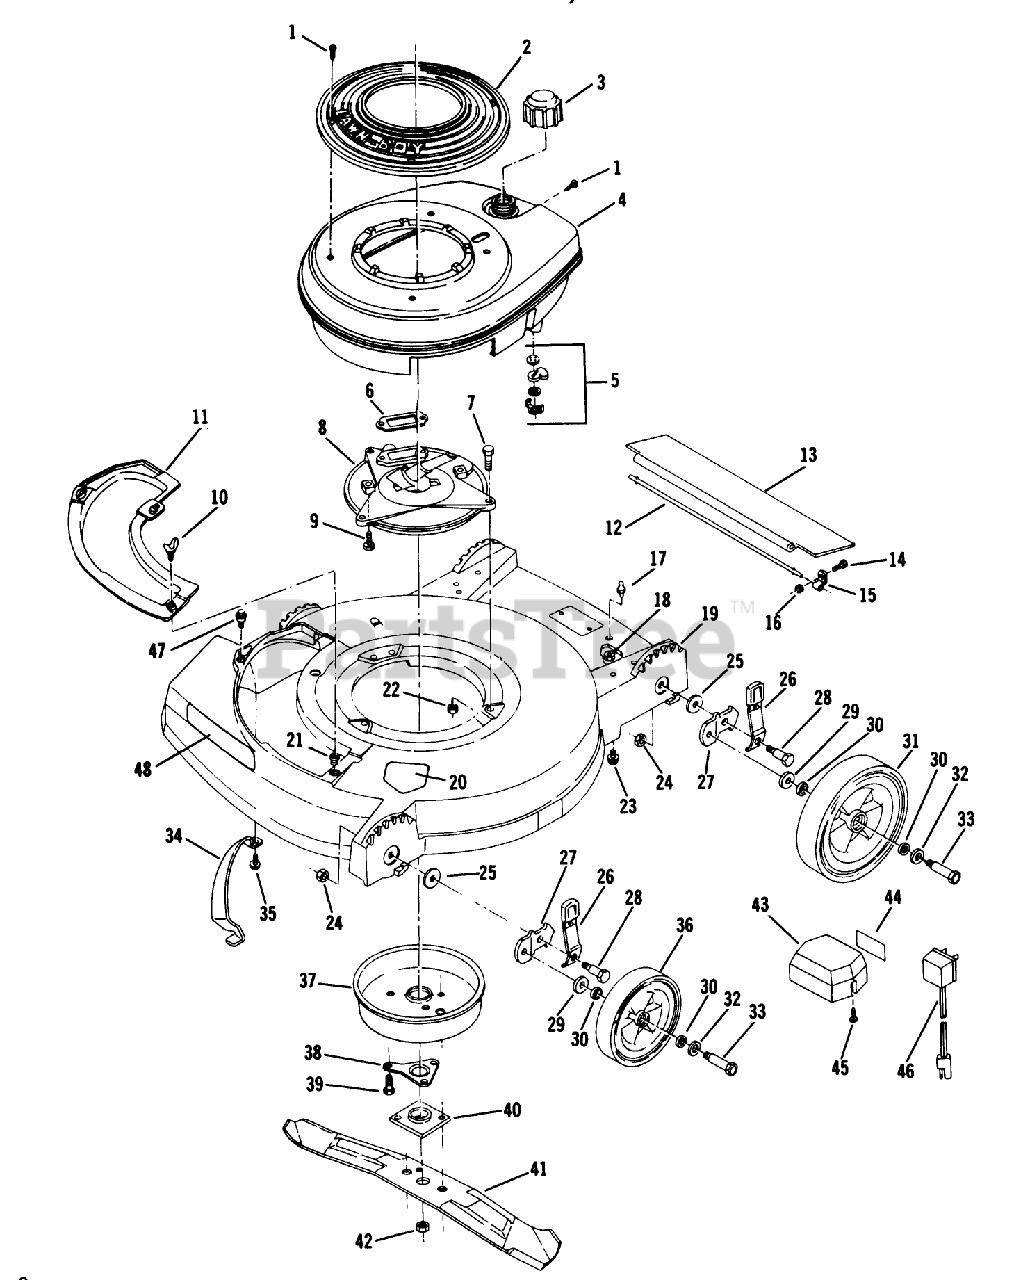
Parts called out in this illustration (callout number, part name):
1	SCREW - SELF TAPPING
3	FUEL CAP & INSERT
5	SHUT OFF VALVE KIT
7	SCREW-HH
9	SCREW V
10	WING SCREW LAWRE
12	ROD 21" ADVANCE
15	CLAMP ROD KMC
16	LOCKNUT E
22	NUT-LOCK F
24	LOCKNUT
29	WASHER WROUGHT
33	BOLT WHEEL
34	BAR-TOE
36	WHEEL & TIRE KIT
37	MUFFLER COVER F
38	SUPPORT F
40	PLATE AND COLLAR ASM
42	NUT-BLADE
